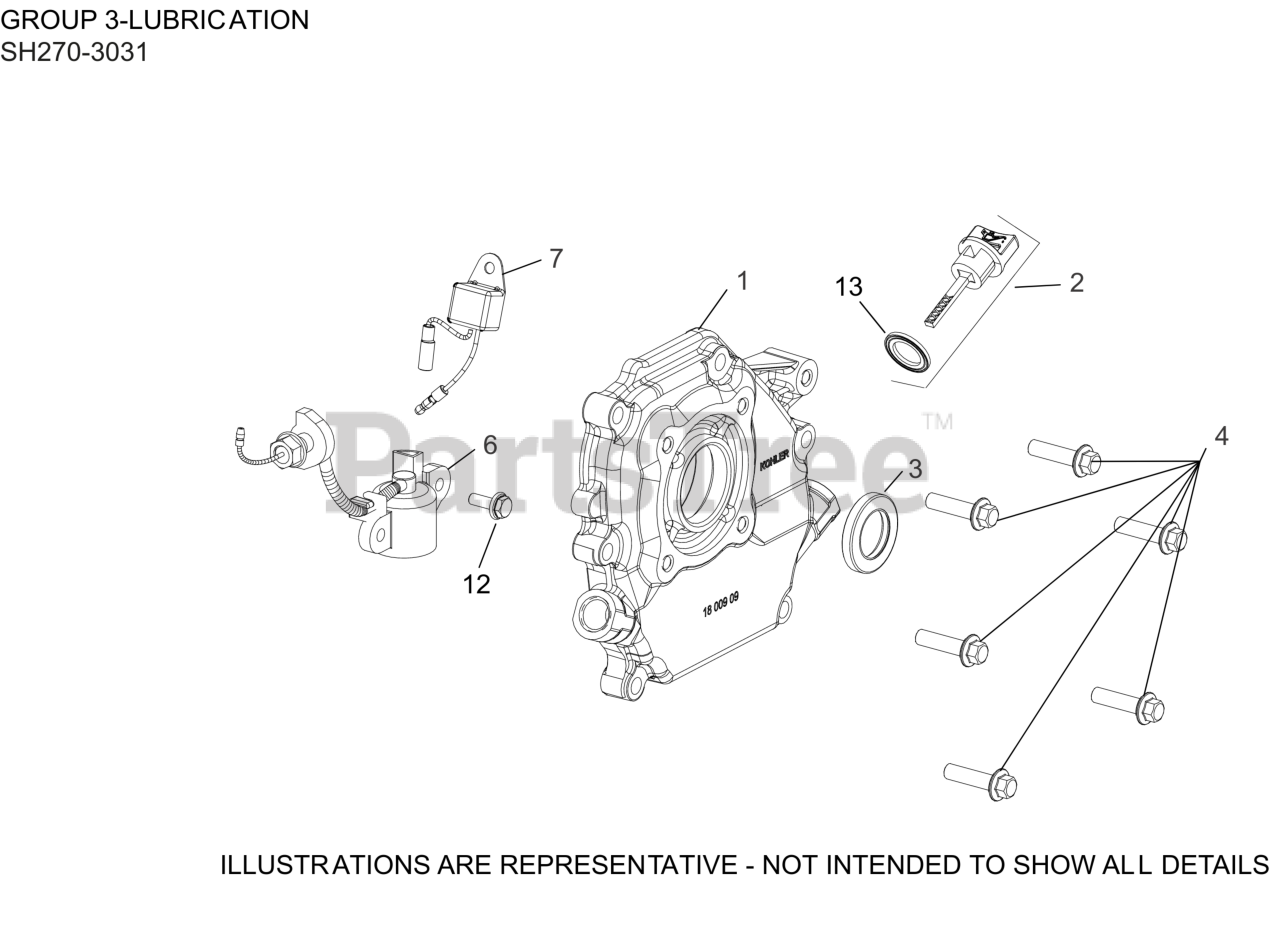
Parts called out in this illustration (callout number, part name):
1	PLATE, CLOSURE & BEARING
2	DIPSTICK ASSEMBLY
3	SEAL - USE 17 032 29-S
4	SCREW, CLOSURE PLATE
6	SWITCH, OIL SENSOR ASSEMBLY
7	CONTROL, OIL ALERT UNIT
12	SCREW, M6 X 16
13	SEAL, DIPSTICK
15	DIPSTICK - USE 17 038 08-S
